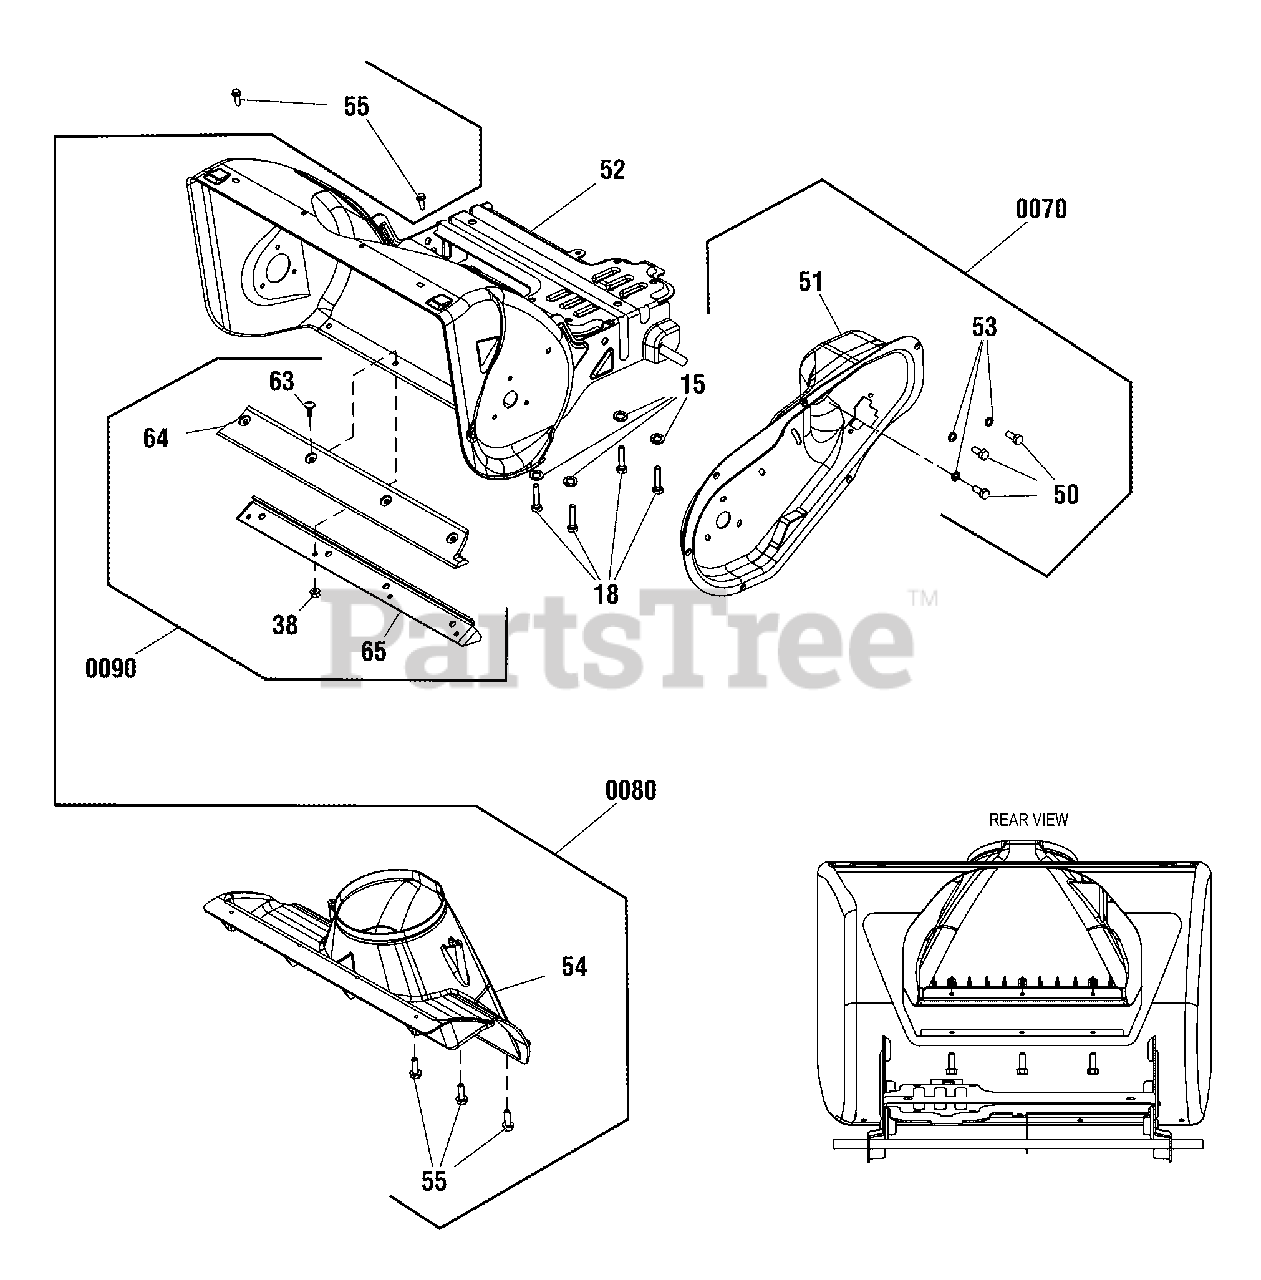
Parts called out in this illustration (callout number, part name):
15	*WASHER, Spring, M10
18	*SCREW, Hex Head, Trilobular, 3/8-16x1-1/4
38	*LOCKNUT, Nylon, Hex, 1/4-20
50	*SCREW, Hex Head, Cap, 5/16-24x.625
51	*HOUSING, Drive
52	*HOUSING, Auger
53	*LOCKWASHER, Split, 5/16
54	*CHIMNEY
55	*SCREW, Hex Washer, Self-Tapping
63	*SCREW, Allen Head, 1/4-20x.625
64	*BAR, Scraper, Robolon
65	*SUPPORT, Scraper
0070	KIT, DRIVE HOUSING
0080	KIT, CHIMNEY
0090	KIT-SCRAPER BAR
